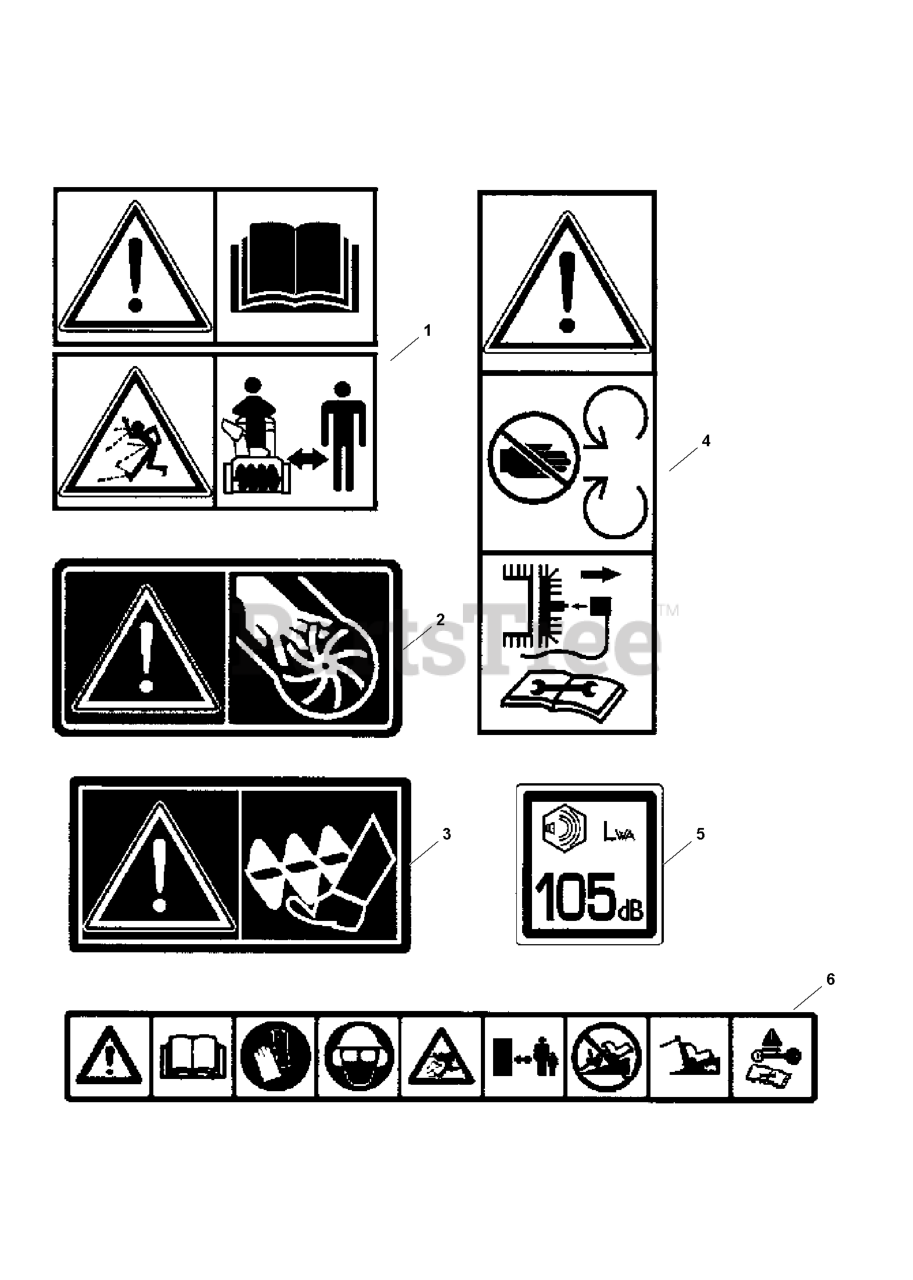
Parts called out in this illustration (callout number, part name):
1	DECAL.AUGER."
2	DECAL.CHUTE.SAFETY.EU/SC.17
3	DECAL.AUGER.SAFETY.
4	DECAL.BELT.GUARD.
5	DECAL.NOISE.LEV.105/CE.EAC.UKR
